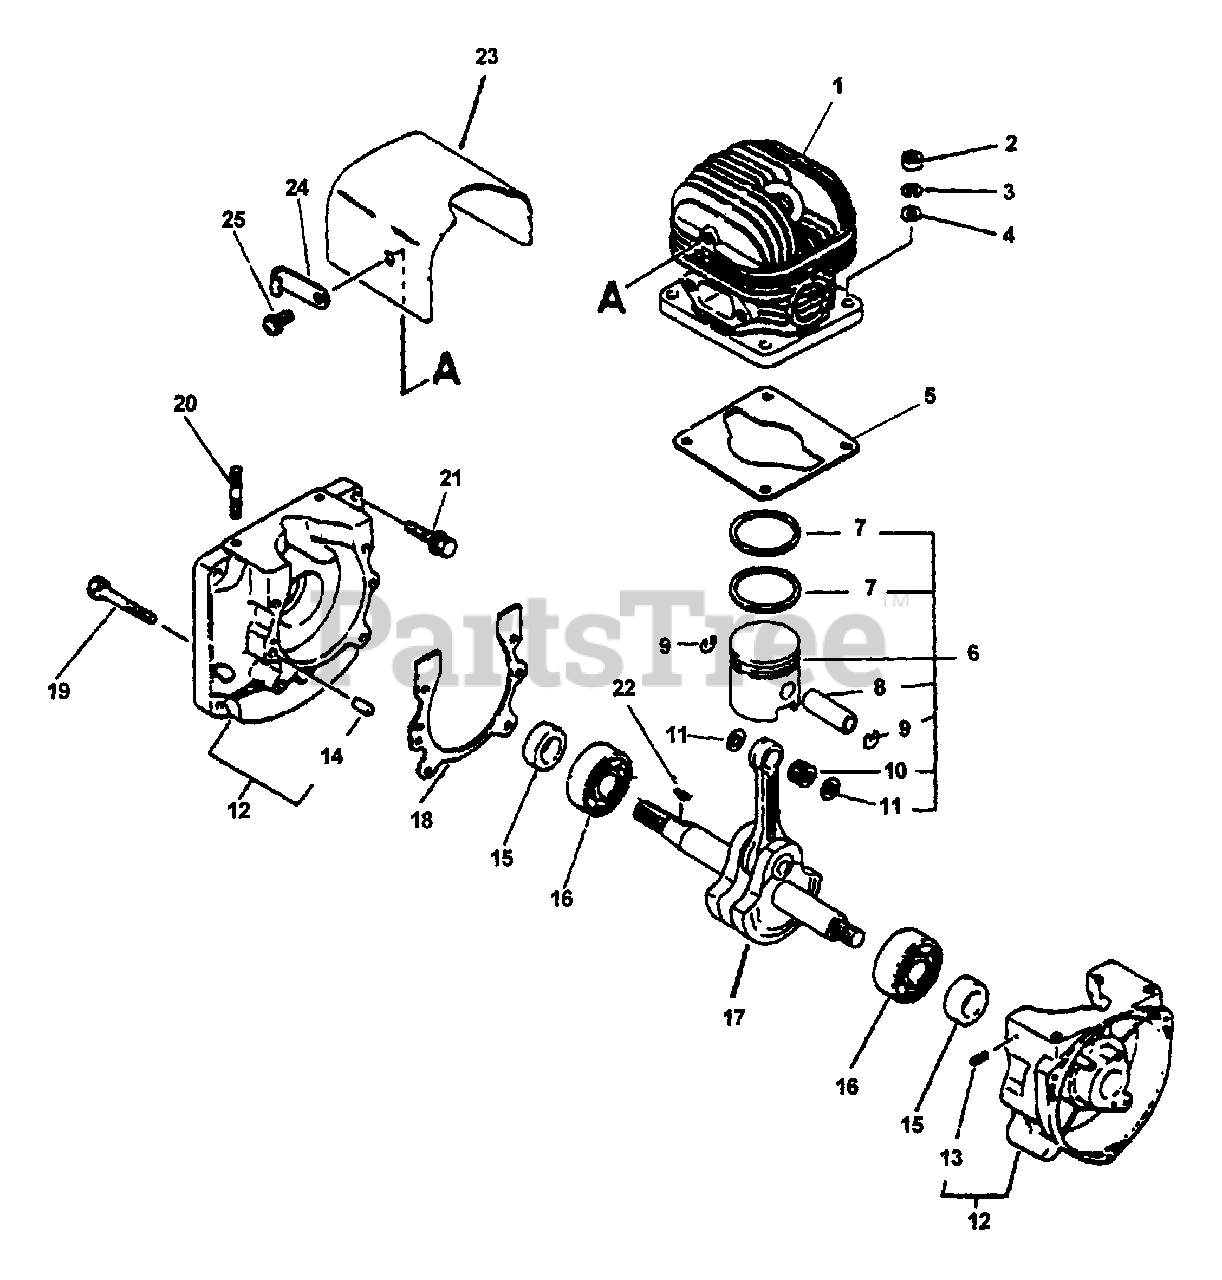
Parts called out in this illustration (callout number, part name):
1	CYLINDER
2	NUT, HEX M6
3	WASHER, SPRING 6
4	WASHER 6.5×11.5×0.8
5	GASKET, CYLINDER
6	PISTON KIT
7	RING, PISTON
8	PIN, PISTON
9	RING, SNAP 8
10	BEARING, NEEDLE 10
11	WASHER, THRUST
12	CRANKCASE KIT
13	CONNECTOR
14	PIN, LOCATING 5×10
15	SEAL, OIL
16	BEARING, BALL 6202
17	CRANKSHAFT ASSY
18	GASKET, CRANKCASE
21	BOLT - 5×25
23	COVER, CYLINDER
24	CLIP, CORD
25	BOLT 6×10
